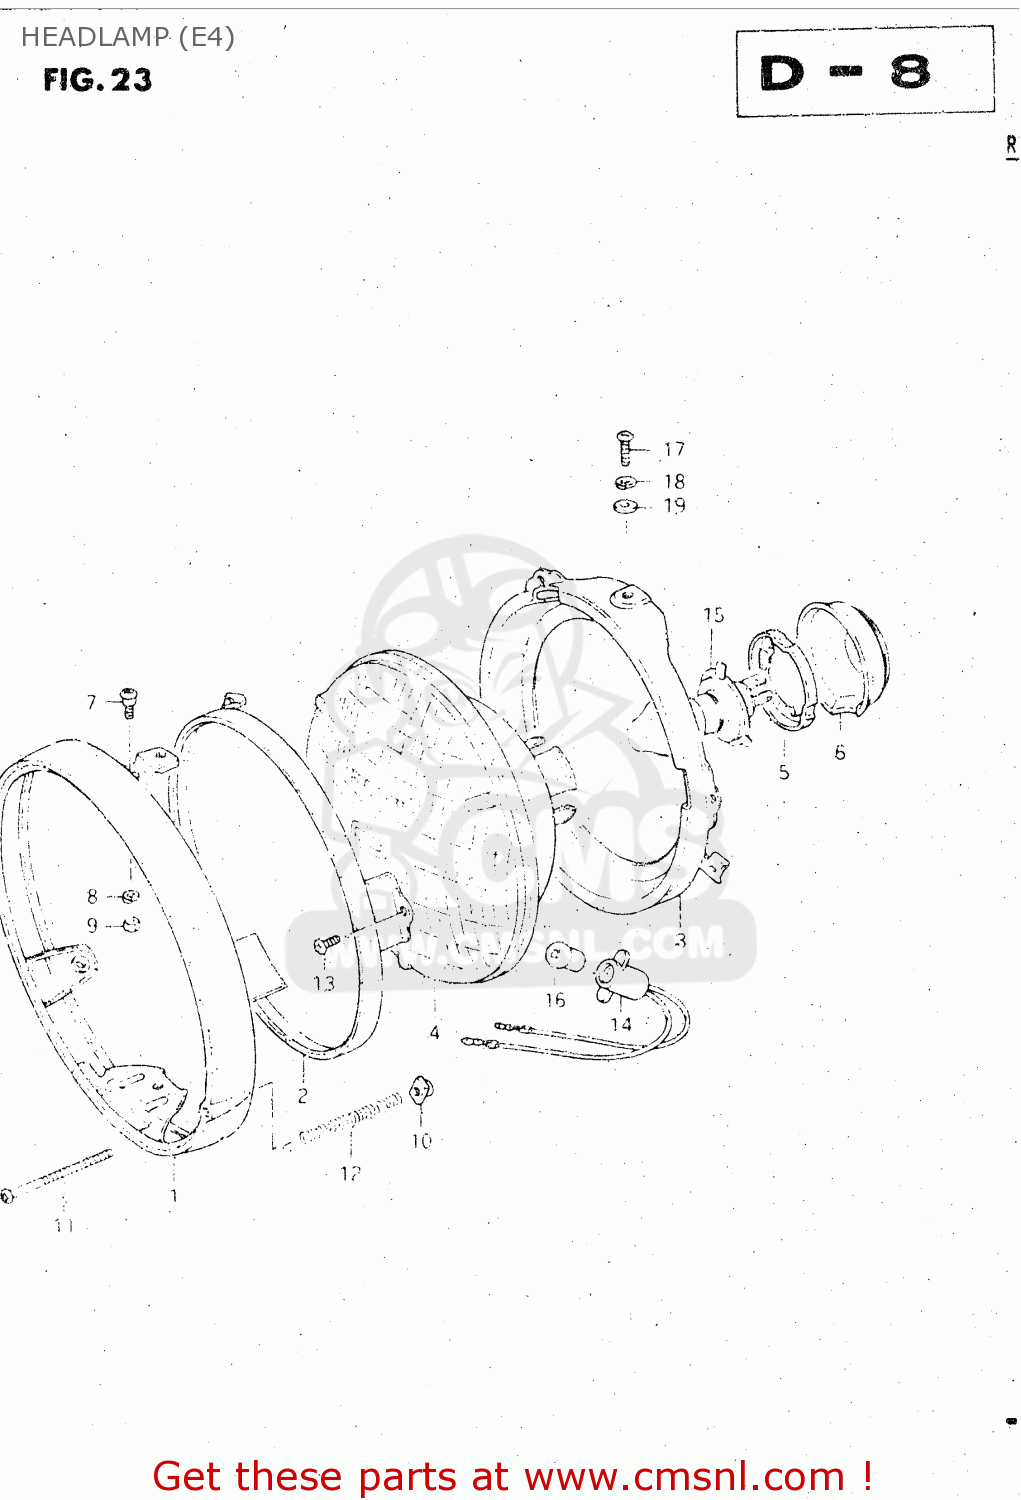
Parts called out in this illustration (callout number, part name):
1	RIM
2	RETAINING RING
3	RING
4	UNIT,HEAD LAMP
5	SETTING,BULB
6	COVER,HEADLAMP SOCKET
7	H/LAMP LENS UNIT FITING SCRE
8	LOCK WASHER
9	NUT
10	NUT
11	SPRING,ADJUSTING
12	SCREW
13	SOCKET
14	BULB (12V, 60/55W, H4)
15	BULB(12V4W)
16	SCREW
17	WASHER,LOCK
18	WASHER
